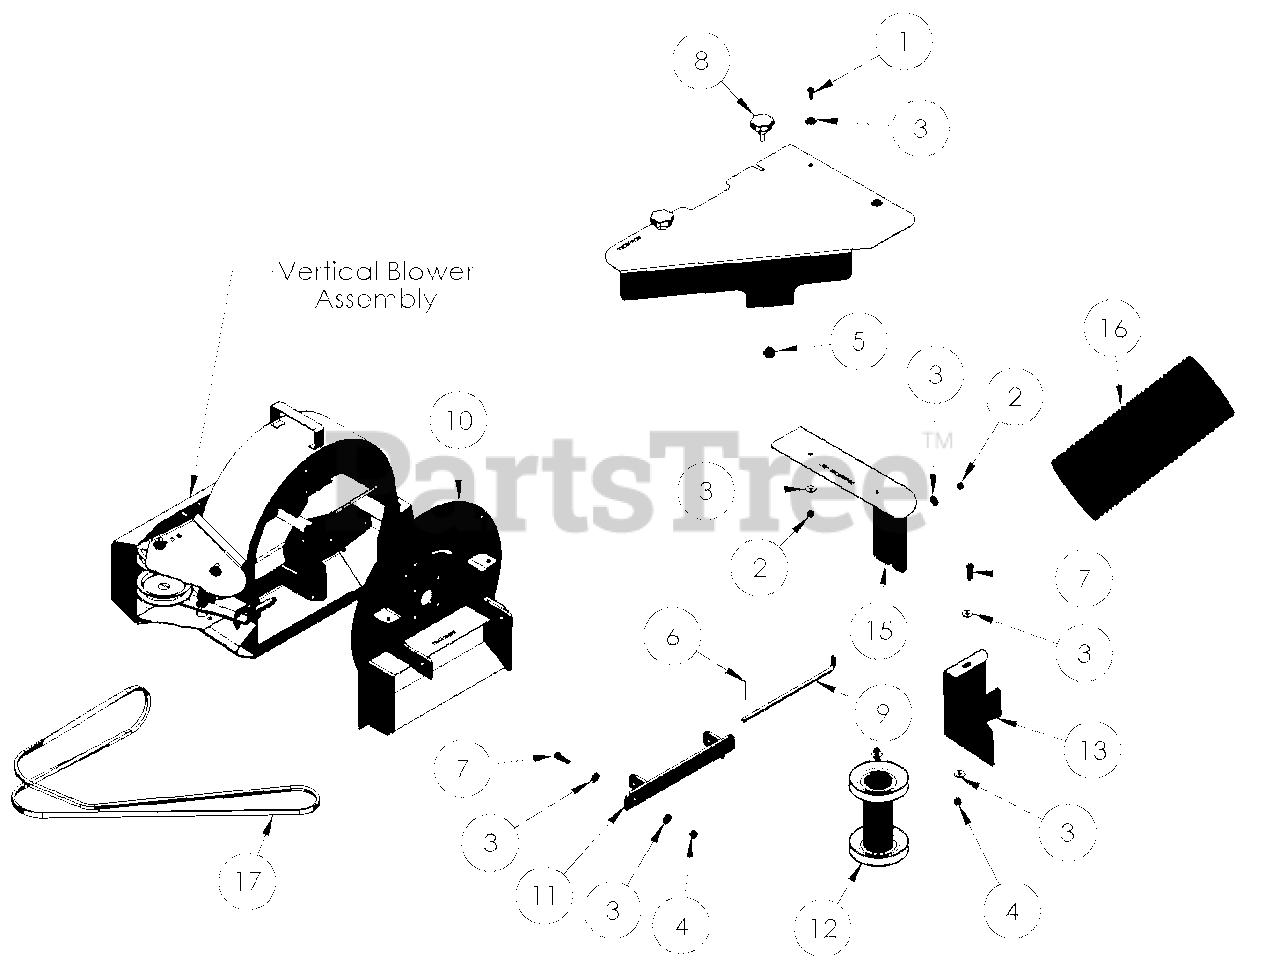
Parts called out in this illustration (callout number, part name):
1	Cap Screw 5/16- 18 X .75
2	5/16- 18 Nylon Insert Nut
3	5/16" Flat Washer
4	3/8- 16 Nylon Insert Nut
5	Rubber Bumper
6	Hair Pin, 0.091 X 1.875
7	Cap Screw 3/8- 16 X 1 1/4 Lg
8	Release Knob
9	Mounting Pin, 'L' 10.25" EL
10	Blower Mount, Pro Series
11	Deck Bracket, 60" Pro Series
12	Double Pulley, Pro Series
13	Deck Seal, 60" Pro Series
14	Front Pulley Cover, PRO Series 60-66
15	Pulley Cover Leg, 60" Pro Series
16	Hose, 6" X 48" Lg.
17	Belt, Aramid Cord 105"
